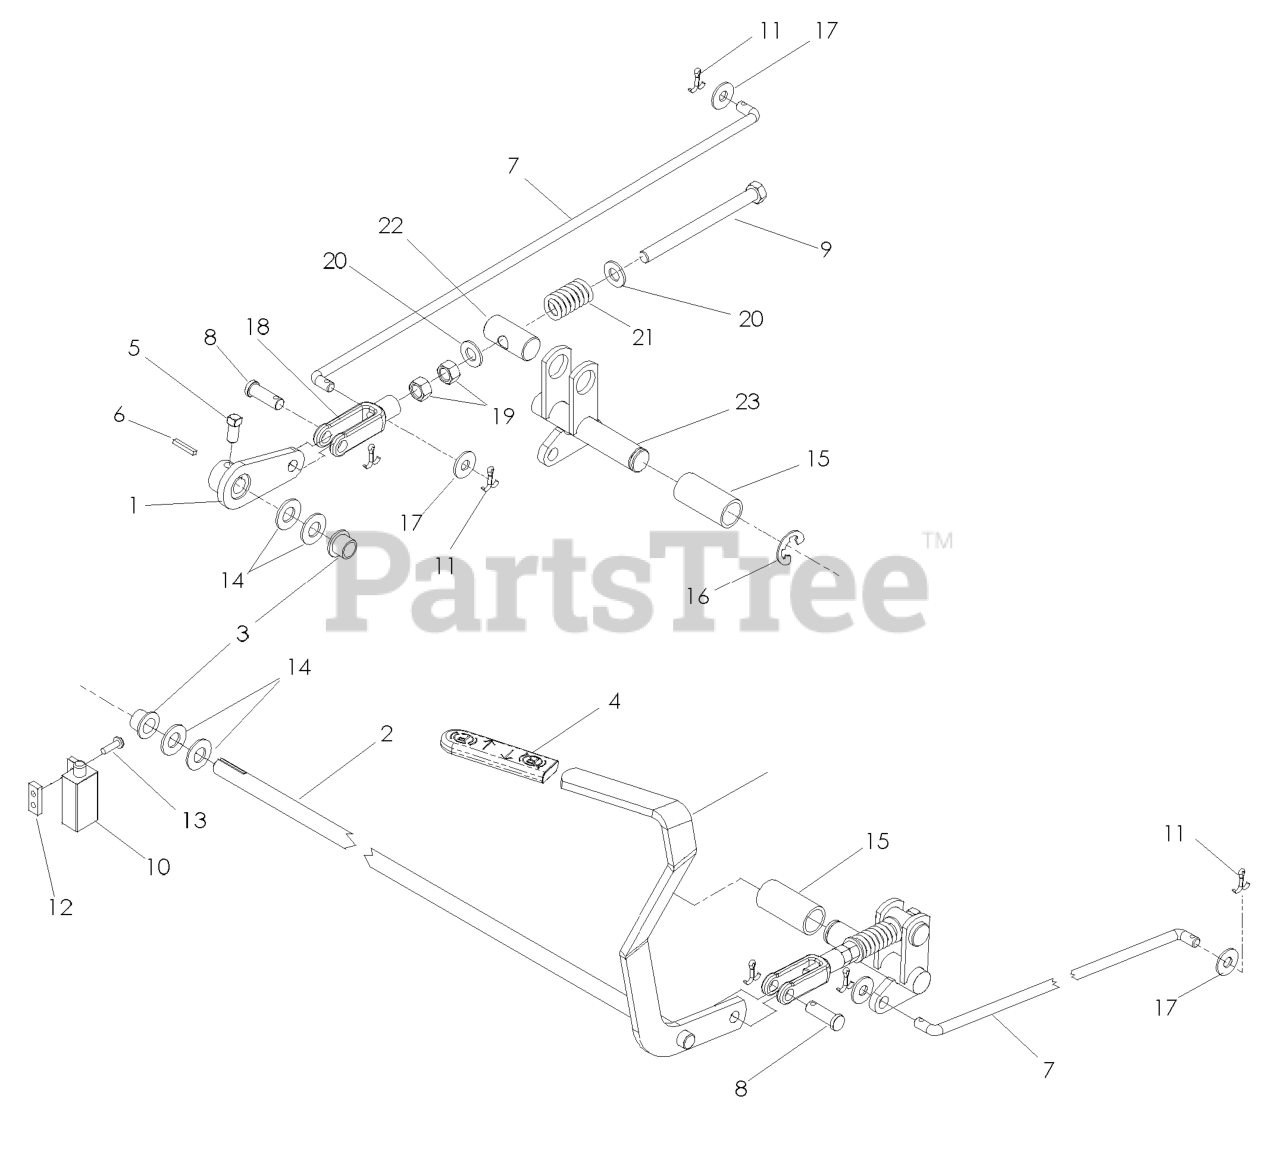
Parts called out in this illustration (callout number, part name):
1	BRAKE ARM WELDMENT
4	GRIP, PARK BRAKE
5	SCREW 5/16C X 5/8 SQ HEAD
7	BRAKE LINKAGE BAR
8	CLEVIS PIN 3/8 X 1 1/8
9	HCS 3/8F X SPECIAL
11	RP_COTTER PIN 1/8 X 3/4
12	TAPPED PLATE
13	SCREW #10-24 X 5/8
14	WASHER, 7/16 DISC SPRING
15	BRONZE BEARING
16	E RING 3/4
17	WASHER 5/16 FLAT
18	YOKE-3/8-24 PLTD
20	WASHER 3/8 SAE FLAT
22	TRUNION PIN
